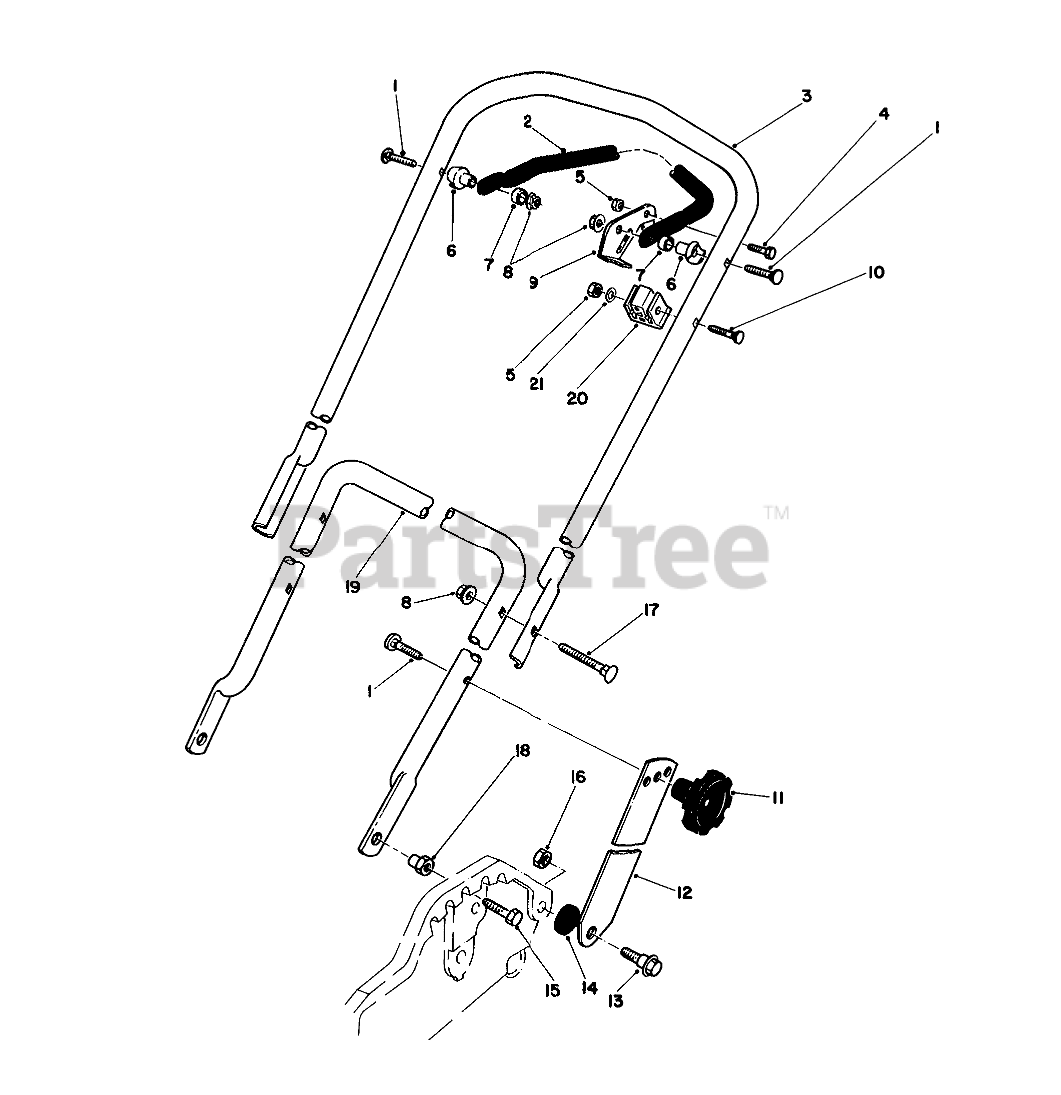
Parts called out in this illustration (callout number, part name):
1	5/16-18 X 2 HNDLE SCREW
2	CONTROL BAR
3	UPPER HANDLE
4	SCREW-HH
5	NUT-LOCK, NI
6	SPACER-SUPPORT
7	SPACER-NYLON
8	NUT-LOCK, NI
9	LEVER-CONTROL
10	HANDLE SCREW
12	Handle Latch
13	SCREW-SHOULDER
14	SPACER
15	SCREW-HH
16	NUT-LOCK, NI
17	SCREW
18	HANDLE PIVOT NUT
19	LOWER HANDLE
20	SUPPORT-CABLE
21	WASHER-FLAT
